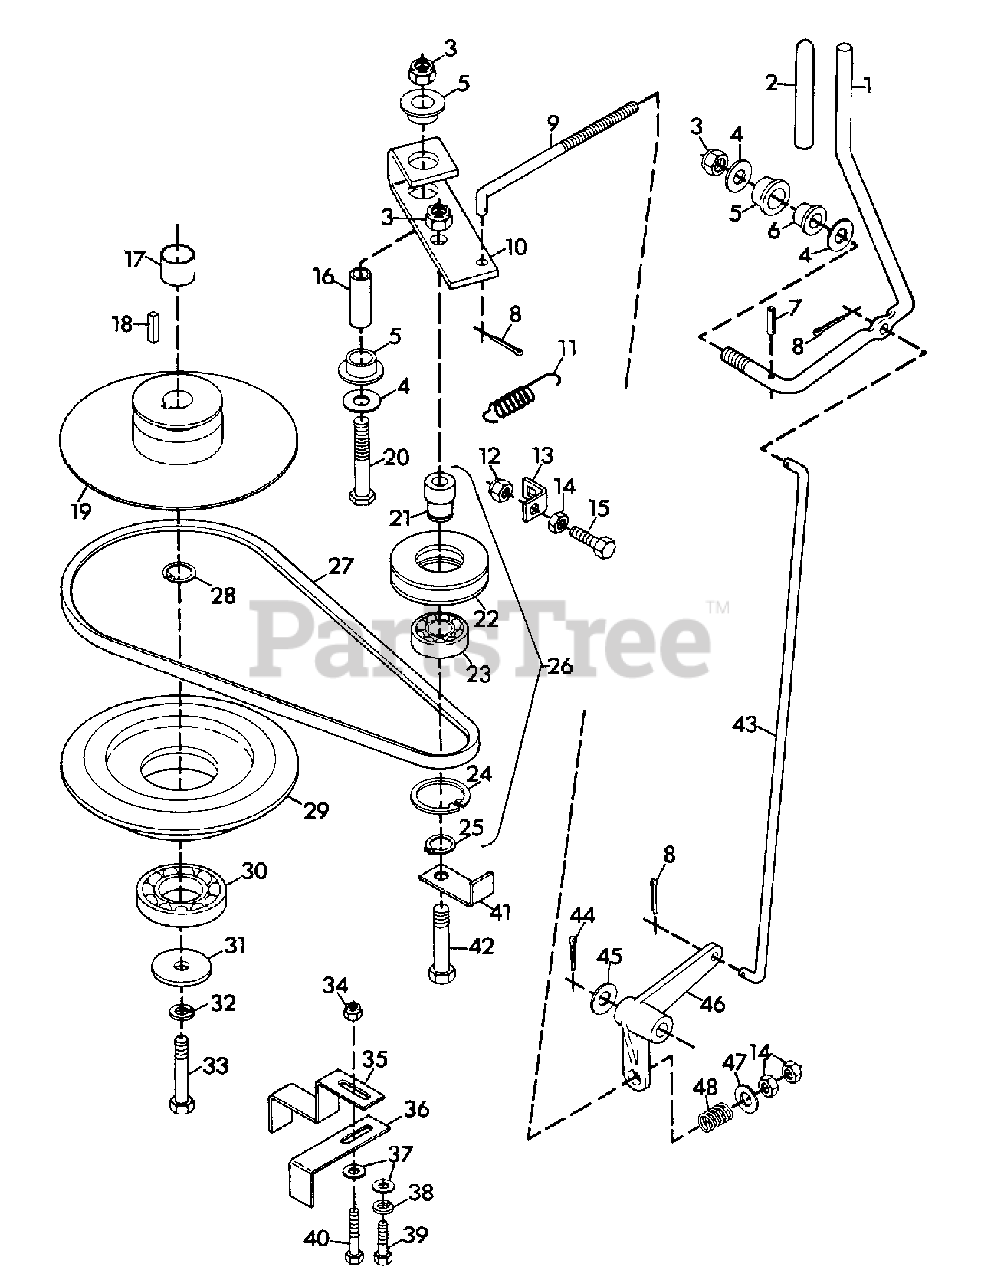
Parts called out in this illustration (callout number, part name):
1	LEVER, PTO ACTUATING
2	GRIP, PTO LEVER
3	NUT, LOCK 1/2-13
4	WASHER, FLAT .531X1.250X.100
5	BUSHING, NYLON .76X1X.6 FLANGE
6	BUSHING, .513X.750X.625
7	PIN, SPRING .187X1.000
8	PIN, COTTER .09X.75
9	ROD, PTO CLUTCH ACTUATING
10	ARM, IDLER PIVOT
11	SPRING, PTO RETURN
12	NUT, LOCK 3/8-16
13	TAB, SPRING
14	NUT, HEX 3/8-16
15	BOLT, HEX 3/8-16X1.50
16	SPACER
17	SPACER, ELECTRIC CLUTCH
18	KEY, SQUARE .250X1.250
19	HUB, PTO AND DRIVE CLUTCH
20	BOLT, HEX 1/2-13X2.75 SPECIAL
21	BUSHING
22	SHEAVE, IDLER
23	BEARING, BALL
24	RING, RETAINING
25	RING, RETAINING
26	ASSEMBLY, IDLER SHEAVE
27	V-BELT, PTO CLUTCH
28	RING, RETAINING
29	SHEAVE, MOWER CLUTCH
30	BEARING, BALL 1.574X3.149X.708
31	WASHER, SPECIAL
33	BOLT, HEX 10MMX1.5
35	GUIDE, PTO V-BELT
36	GUIDE, V-BELT
37	WASHER, FLAT .344X.688X.065
38	WASHER, LOCK 8MM SPRING
39	BOLT, HEX M8 X 1.25 30MM
41	GUIDE, BELT
42	BOLT, HEX 1/2-13X2.50
43	ROD, PTO CONTROL
44	PIN, COTTER .125X.75
45	WASHER, FLAT .531X1.062X.095
46	LEVER, PTO CLUTCH
47	WASHER, FLAT .406X.812X.065
48	SPRING, COMP. 1X.78X338
